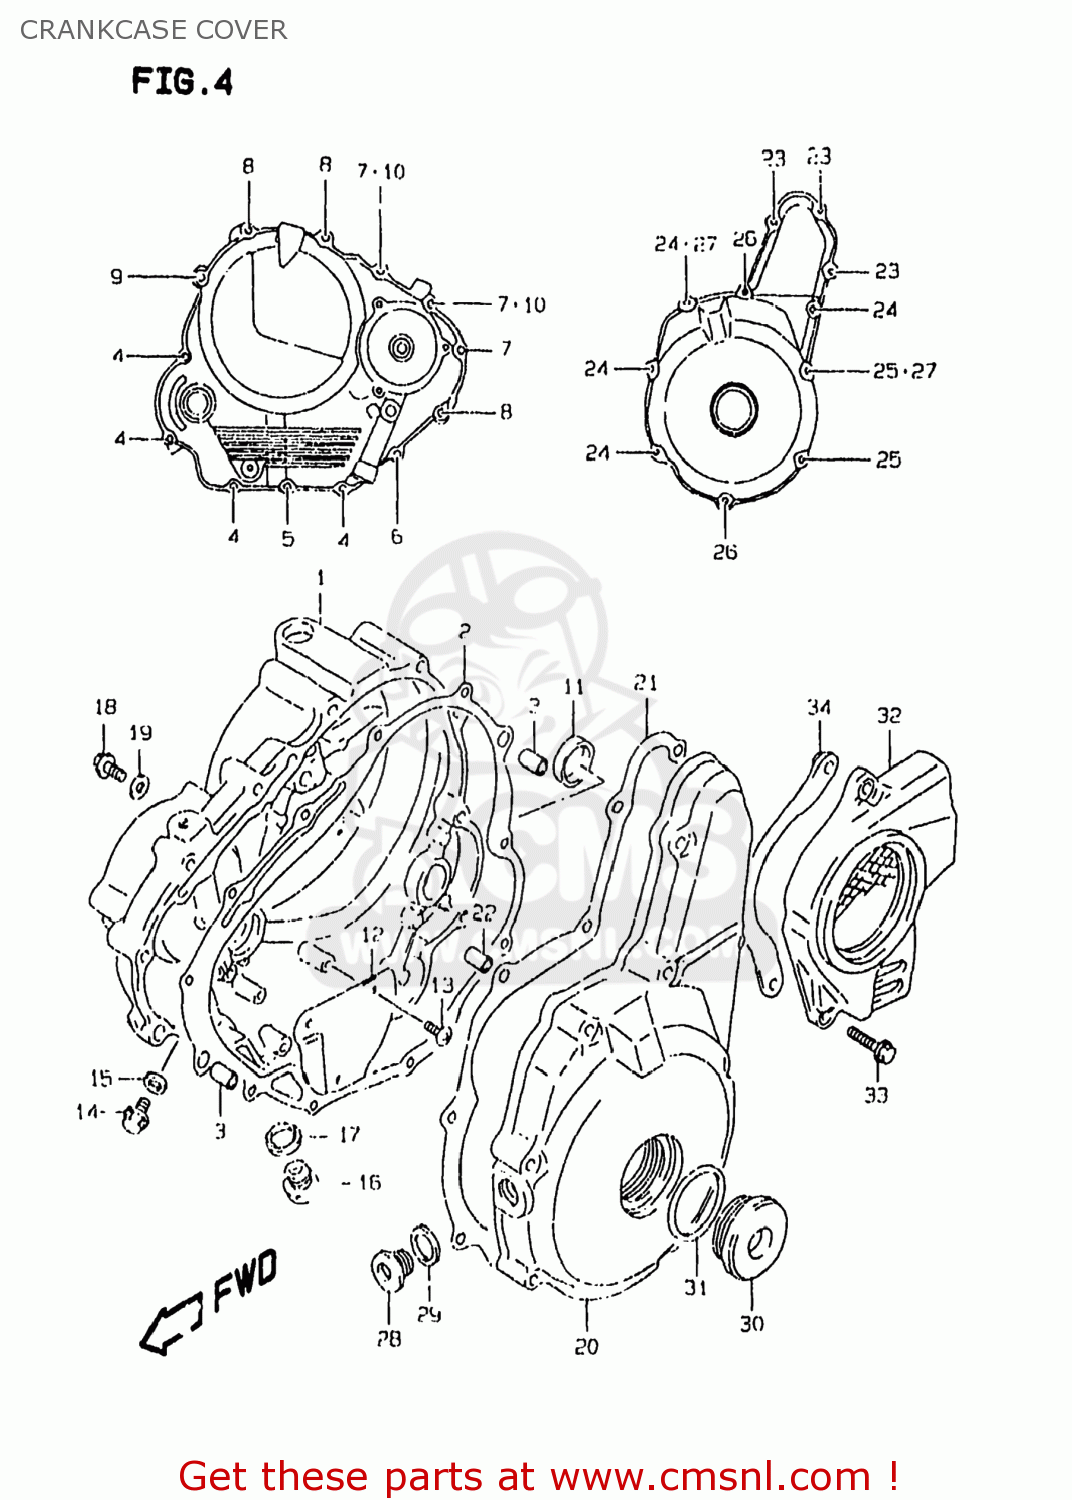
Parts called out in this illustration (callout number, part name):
1	COVER,CLUTCH
2	GASKET,CLUTCH COVER (NAS)
3	PIN
4	SCREW
5	BOLT,G/S SWITC
6	BOLT
7	BOLT
8	BOLT
9	BOLT
10	GASKET(5.8X11X1.2) (NAS)
11	PLUG,CLUTCH COVER KICK
12	SEPARATOR,OIL RETURN
13	SCREW
14	BOLT(6X8)
15	GASKET(6.2X11X1).2 (NAS)
16	PLUG(10X6.8)
17	GASKET(10X14X3.6) (NAS)
18	SCREW(6X10)
19	GASKET(5.8X11X1.2) (NAS)
20	COVER,MAGNETO
21	GASKET,MAGNETO COVER (NAS)
22	PIN
23	SCREW
24	BOLT
25	BOLT
26	BOLT
27	GASKET(5.8X11X1.2) (NAS)
28	PLUG,14X12
29	GASKET(13.8X18.8X4.8) (NAS)
30	PLUG(SILVER)
31	O RING(D:3.1,ID:32.7)
32	COVER,ENGINE SPROCKET
33	SCREW
34	PLATE,FR CHAIN GUIDE
